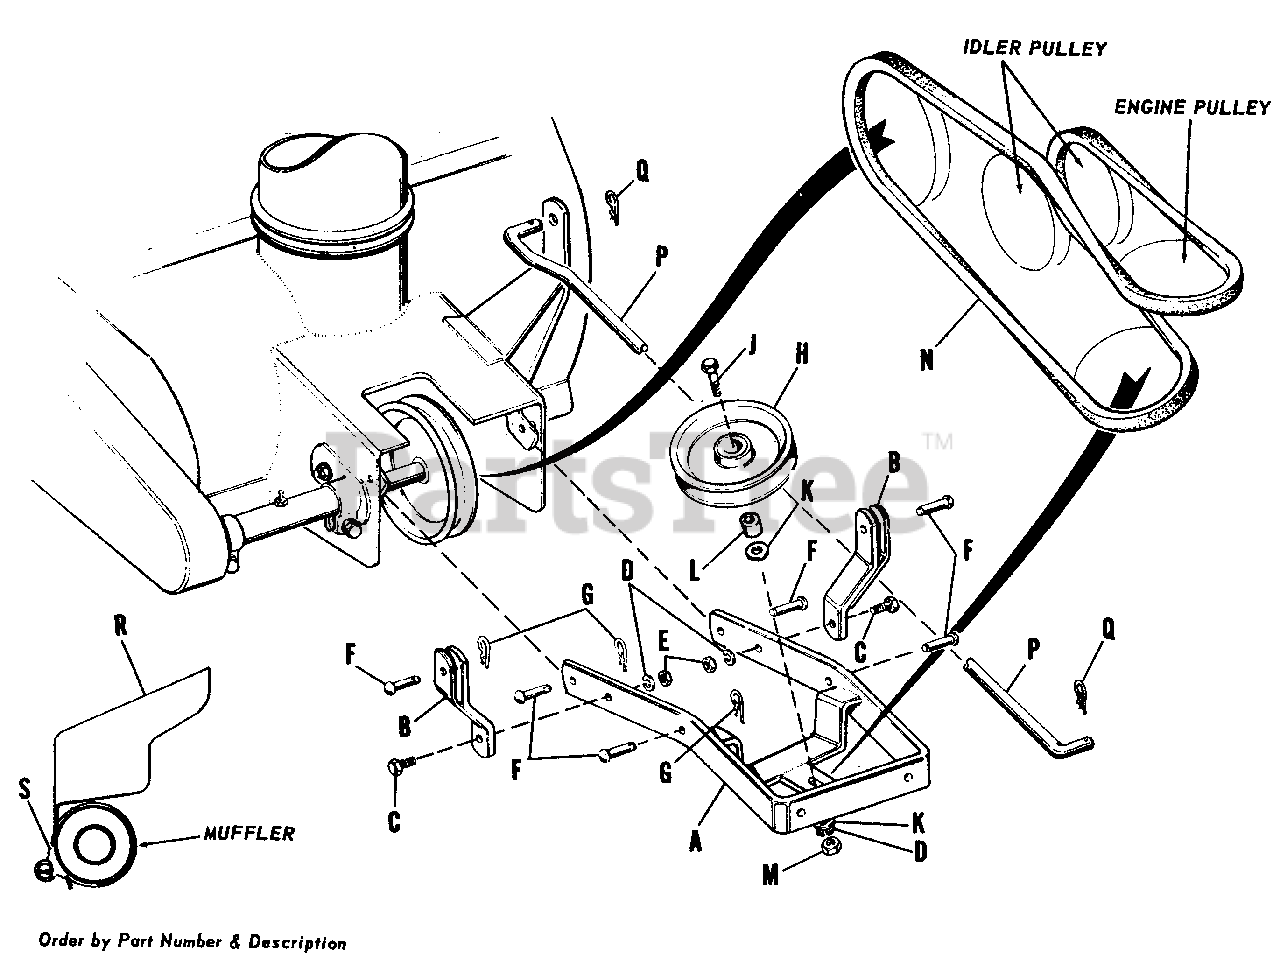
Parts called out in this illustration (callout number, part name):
A	Push Arm Assembly
B	Support Arm Assembly
C	Hex Capscrew, 3/8"-16 x 1-1/4" lg.
D	Lock Washer, 3/8"
E	Hex Nut Full, 3/8"-16
G	Spring Clip
J	Hex Capscrew, 3/8"-16 x 1-3/4" lg.
K	Plain Washer, 3/8"
M	Hex Nut, Full, 3/8"-16
P	Front Lift Rod
Q	Spring Clip
R	Deflector
